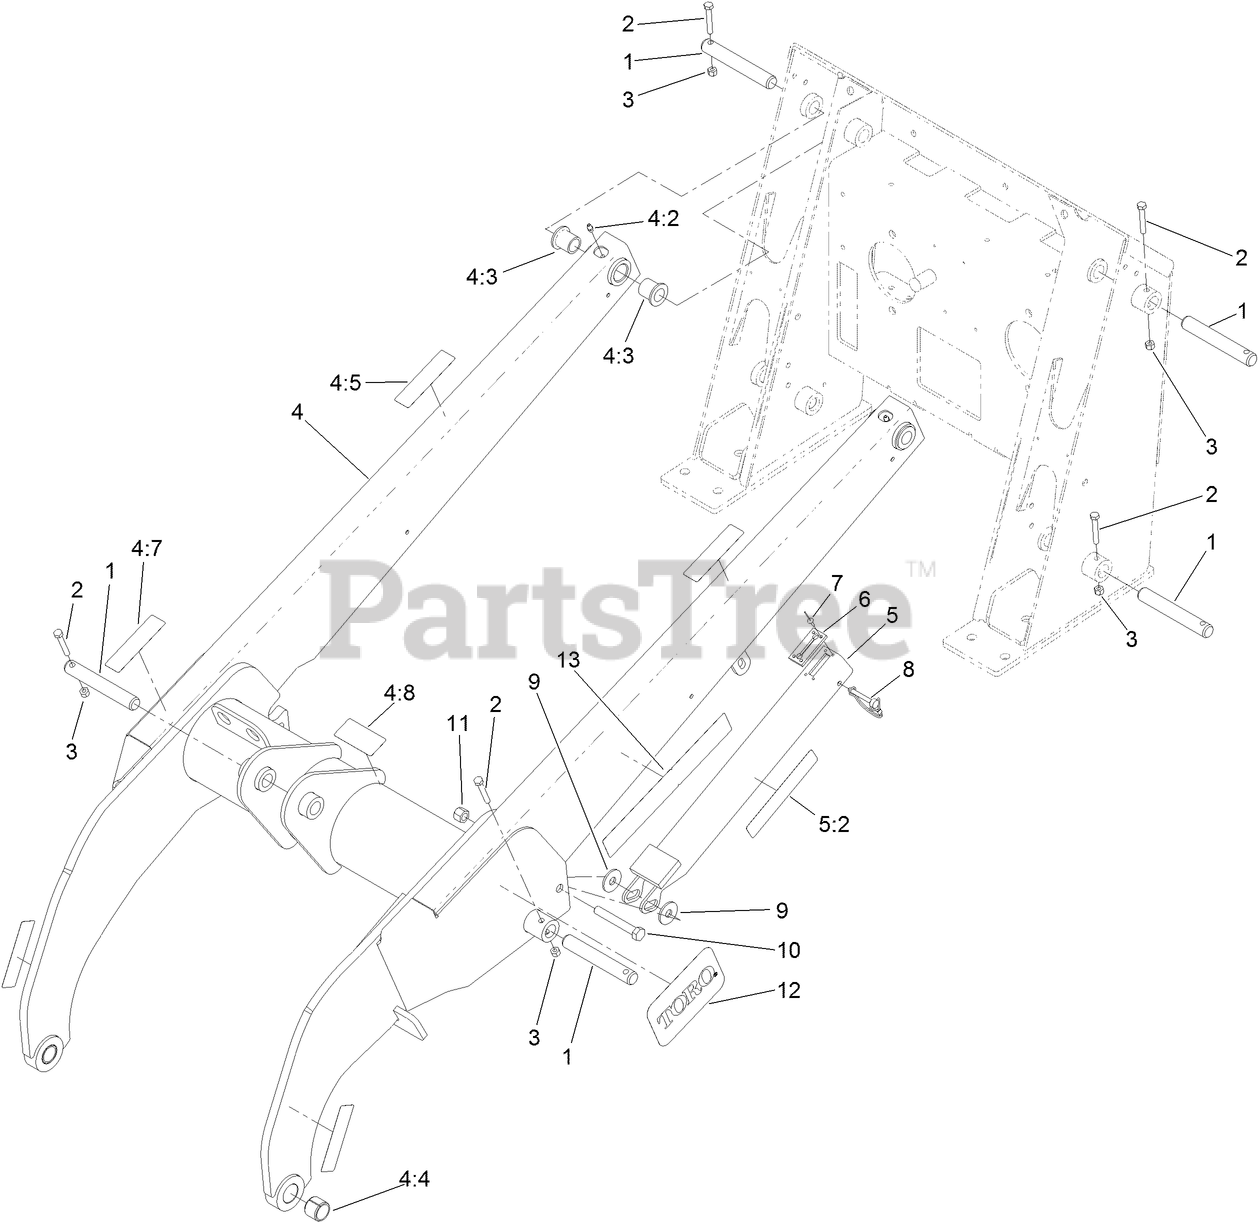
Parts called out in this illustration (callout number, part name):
1	PIN-LOCKING
2	SCREW-HH
3	NUT-LOCK, NI
4	LOADER ARM ASM
4:2	FITTING-GREASE
4:3	BUSHING
4:4	BUSHING-TENSION
4:5	DECAL-WARNING, PINCH
4:7	DECAL-CAUTION
4:8	DECAL-NO RIDER
5	LOCKING ARM ASM
5:2	DECAL-DANGER
6	STOP-RUBBER
7	RIVET
8	PIN-LOCKING
9	WASHER-RUBBER
10	SCREW-HH
11	NUT-LOCK, NI
